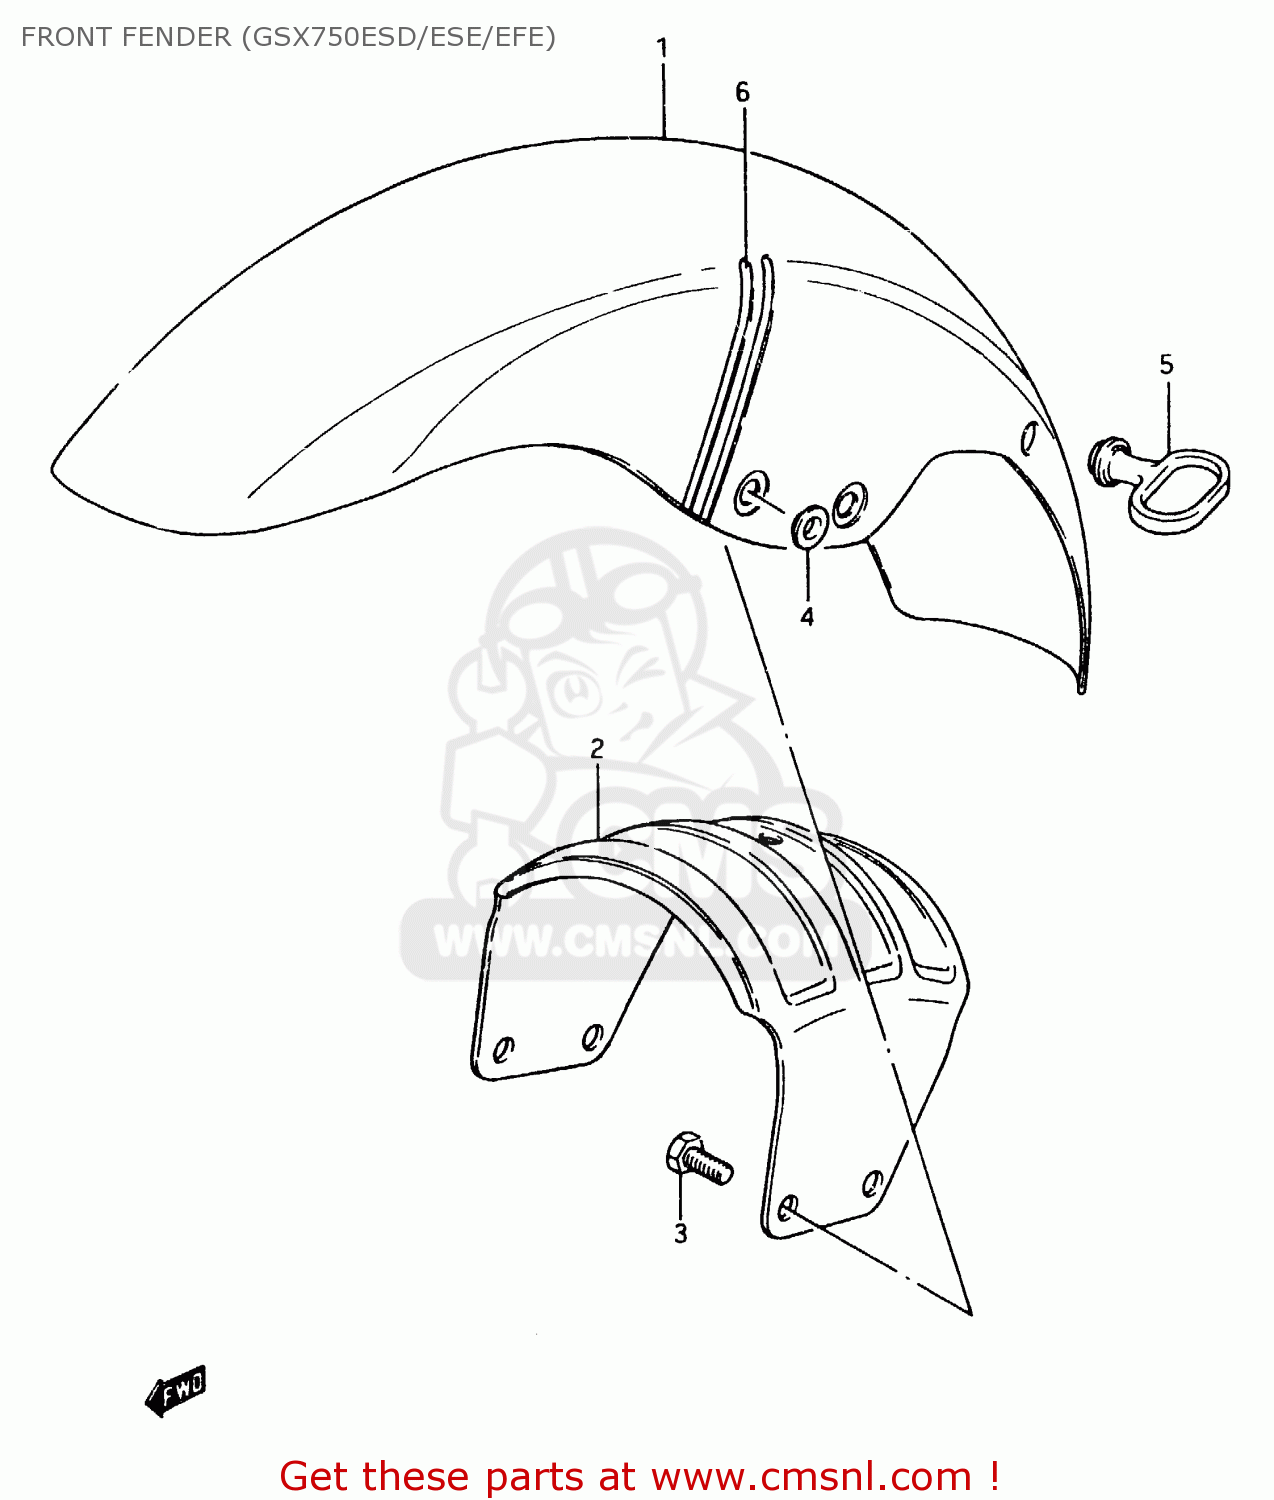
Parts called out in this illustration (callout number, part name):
1	FENDER,FR
2	BRACE,FRONT FENDER
3	BOLT
4	WASHER
5	GUIDE,CABLE
6	DENT,FRONT FENDER
